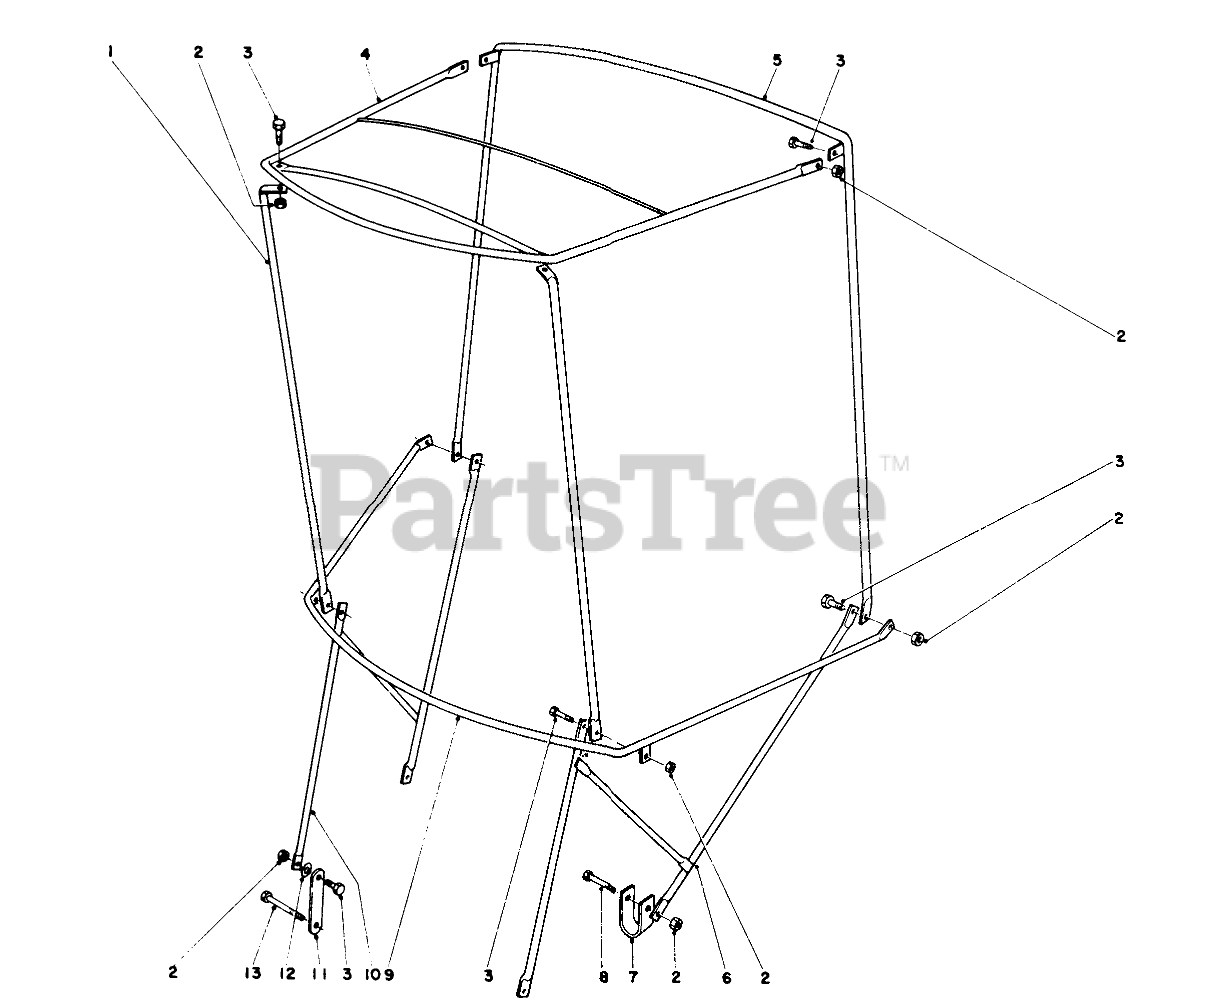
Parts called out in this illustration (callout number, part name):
2	NUT-LOCK
3	SCREW-HH
4	FRAME-TOP
5	BOW-VERTICAL, REAR
6	Attaching Bracket, L.H.
7	U CLAMP
8	SCREW-HH
9	BOW-CURVED
10	Attaching Bracket, R.H.
11	Mounting Strap
12	WASHER-LOCK/EXT
13	SCREW-HH
